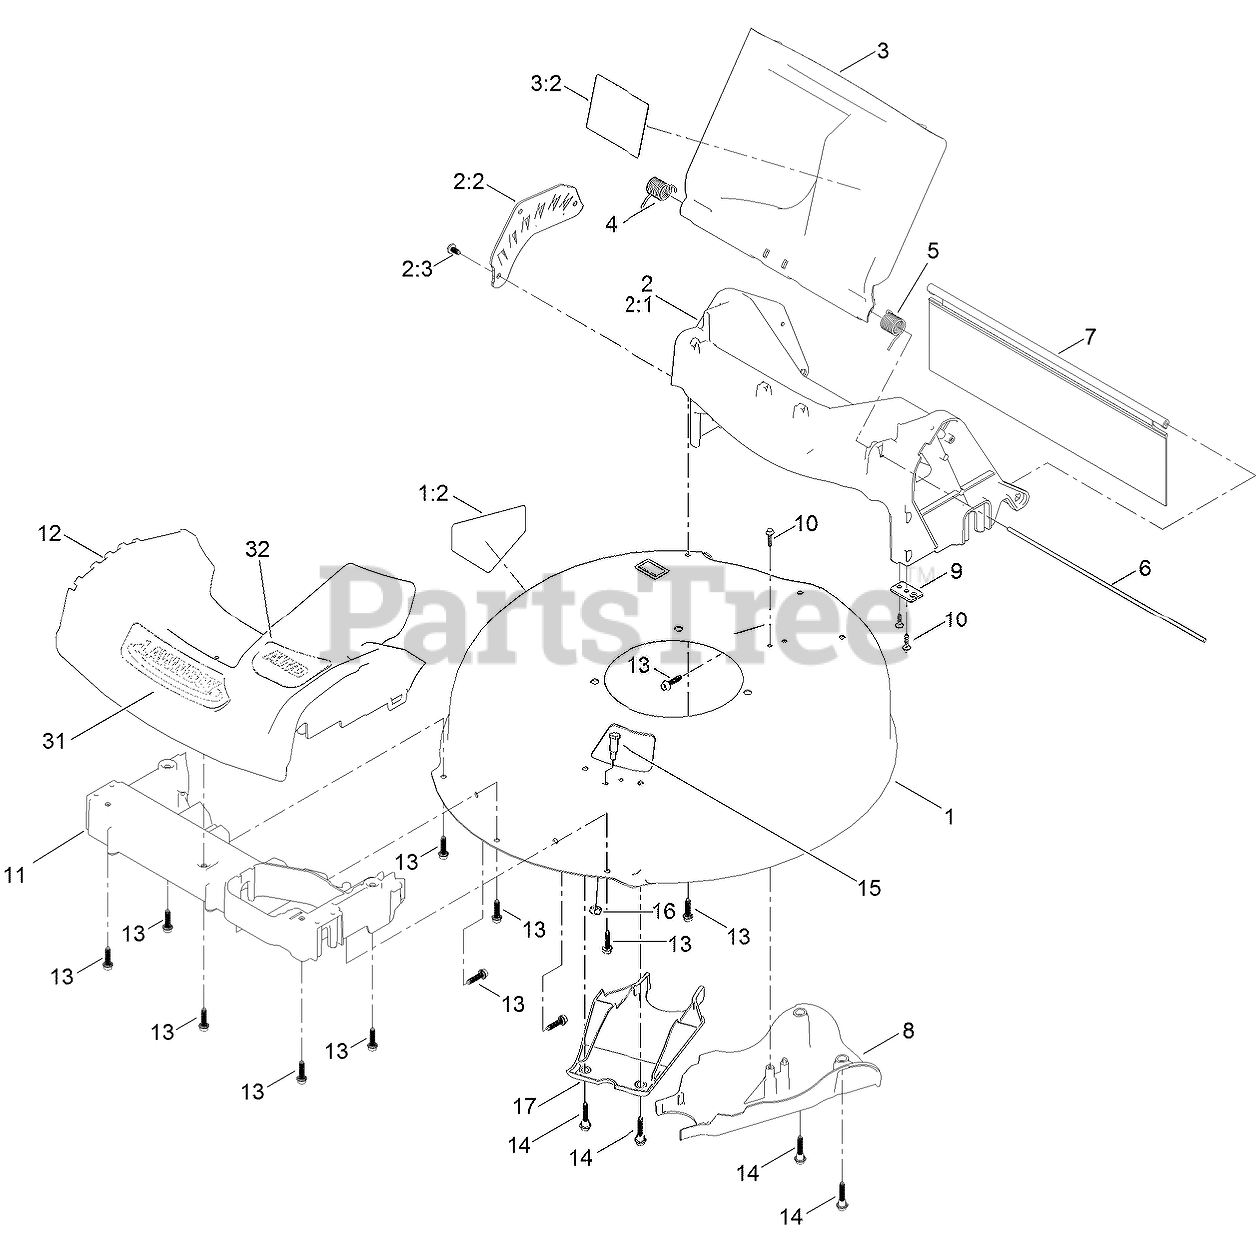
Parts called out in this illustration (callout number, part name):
1	HOUSING ASM
1:2	DECAL-DANGER
2	CHUTE ASM
2:1	CHUTE
2:2	PLATE-HOC
2:3	SCREW-PLASTIC TPH
3	REAR DEFLECTOR ASM
3:2	DECAL-WARNING
4	SPRING-TORSION
5	SPRING-TORSION
6	ROD-DOOR
7	SHIELD-TRAILING
8	COVER-BELT
9	BRACKET-CABLE
10	SCREW-HWH
11	MOUNT-BUMPER
12	BUMPER
13	SCREW-FLANGE, PLASTIC
14	SCREW-SHOULDER, HHF
15	BOLT-SHOULDER
16	NUT-LOCK, NI
17	COVER-BELT, FRONT
31	DECAL-DECK
32	DECAL-COVER
